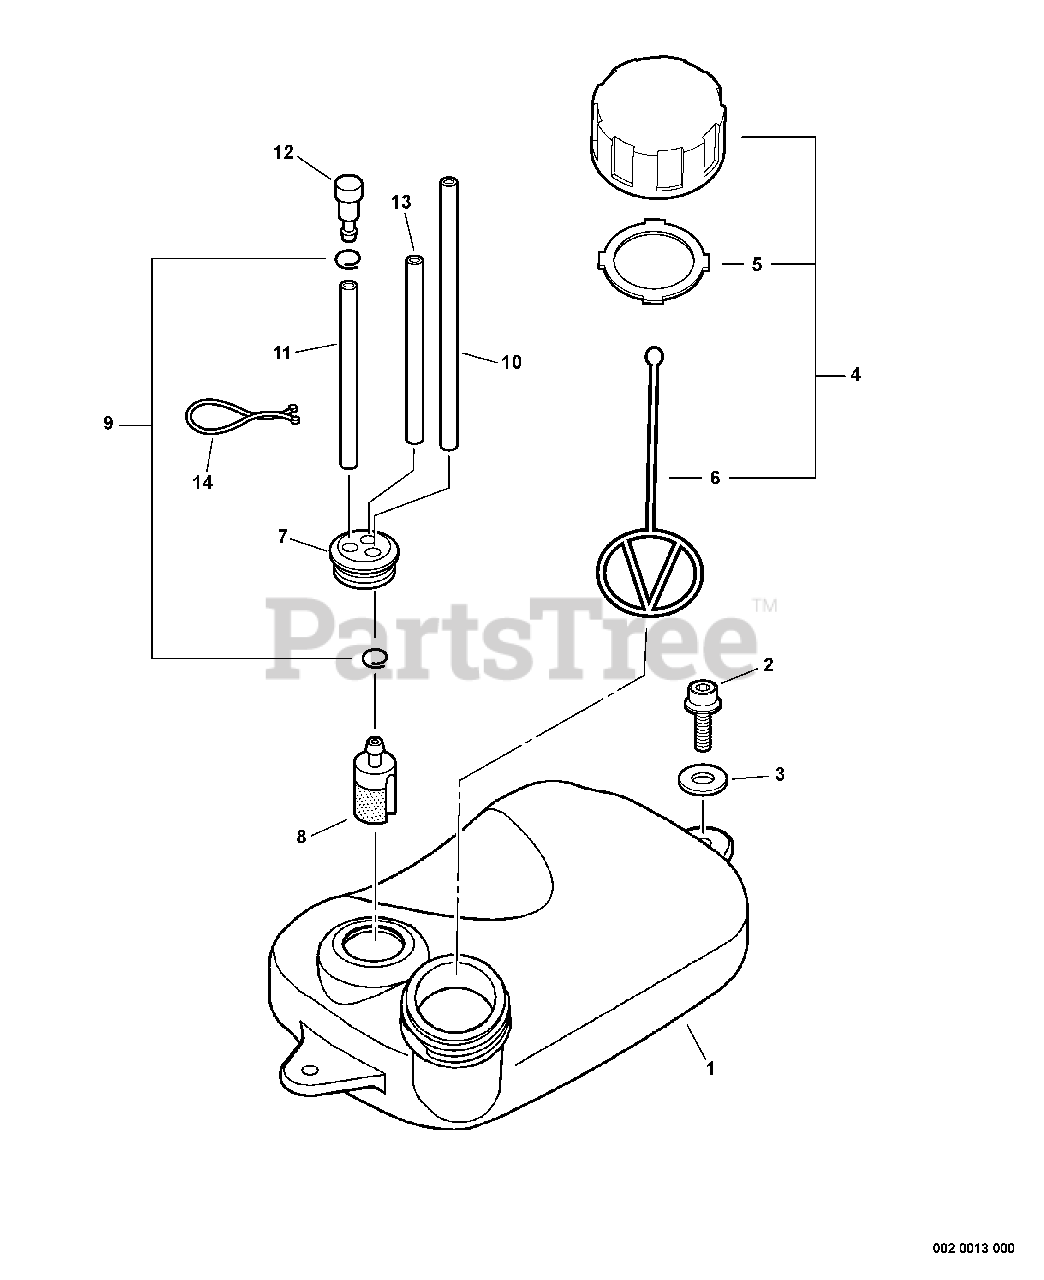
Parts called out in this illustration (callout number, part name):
1	TANK, FUEL
2	SCREW - 5X20
3	WASHER - 5
4	CAP ASSY - ORANGE
5	GASKET, CAP
6	CONNECTOR, CAP
7	GROMMET
8	FILTER, FUEL
9	CLIP - 6
10	PIPE - 3X5X210 -- BLACK
11	PIPE - 3X5X70 -- BLACK
12	VENT, FUEL TANK
13	PIPE, RETURN - 3X6X120
